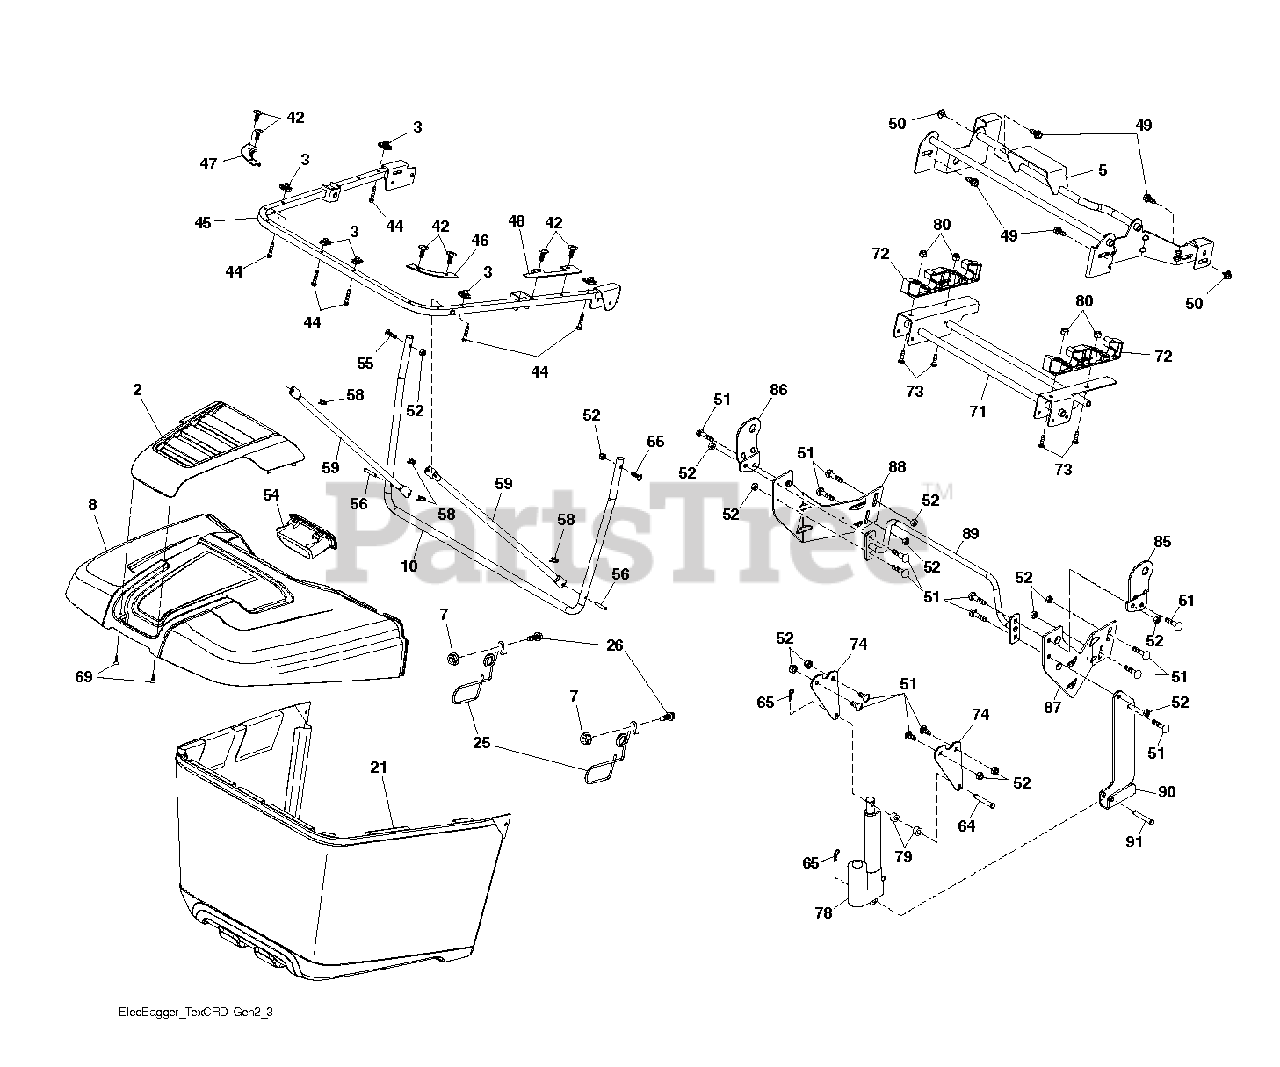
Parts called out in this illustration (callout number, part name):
2	APPLIQUE.BAGGER
3	1/4-20 U NUT
7	NUT T
10	FRAME TEX_CRD_GEN2 BAGGER FRAM
21	BAG FRAME BAGGER ASSEMBLY. HUS
25	LATCH LATCH. BAG. CRD GEN 2
26	SCREW HEX CRT
42	CLIP CHRISTMAS TREE CLIP
45	FRAME TEX_CRD_GEN2 UPPER U FRA
46	CONNECTOR RIGHT BAGGER CORNER
47	CONNECTOR LEFT BAGGER CORNER C
48	BAFFLE BAGGER SIDE CLOSE-OUT
49	BOLT, SHOULDER 5/16-18
50	BOLT, 5/16-18 X 1 3/4
51	BOLT.CARR.SQNK.5/16-18UNC.X3/4
52	NUT.71038.31-18.HEX.NYLOCK
54	HANDLE BAGGER TOP FRONT HANDLE
55	BOLT
56	PIN.CLEVIS.183
58	RETAINER CLIP PM
59	TUBE BAGGER SPREADER TUBE, TEX
65	RETAINER M
69	SCREW,#8.FLAT.HEAD.DRILL.TIP
73	BOLT.CARRIAGE.5/16-18
79	SPACER.NYLON.75" X .4375
80	NUT LOCK HEX FLANGE 5/16-18
85	BRACKET.RH.PIVOT.ELE.DUMPX431
86	BRACKET.LH.PIVOT.ELE.DUMPX431
87	BRACKET.RH.MID.SUP.BAG.TEX.CRD
88	BRACKET.LH.MID.SUP.BAG.TEX.CRD
89	WELDMENT.OFFSET.STRUT.SUP.BLAC
90	BRACKET.ELE.DUMP.ACT.BAG.X431
91	PIN.CLEVIS.(.375 X 1.25)
